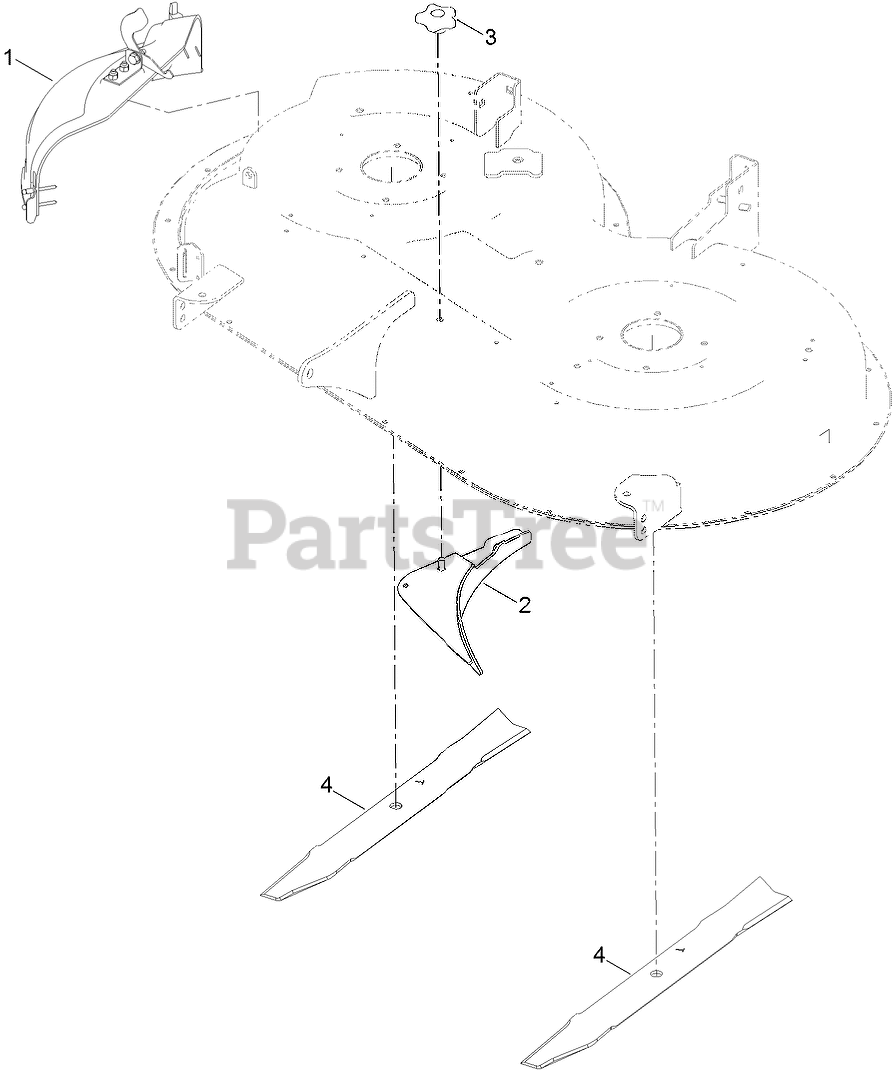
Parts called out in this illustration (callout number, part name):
1	42 INCH MULCH PLUG ASM
2	BAFFLE-CLIPPING
3	KNOB-HANDLE
4	BLADE-MULCH
